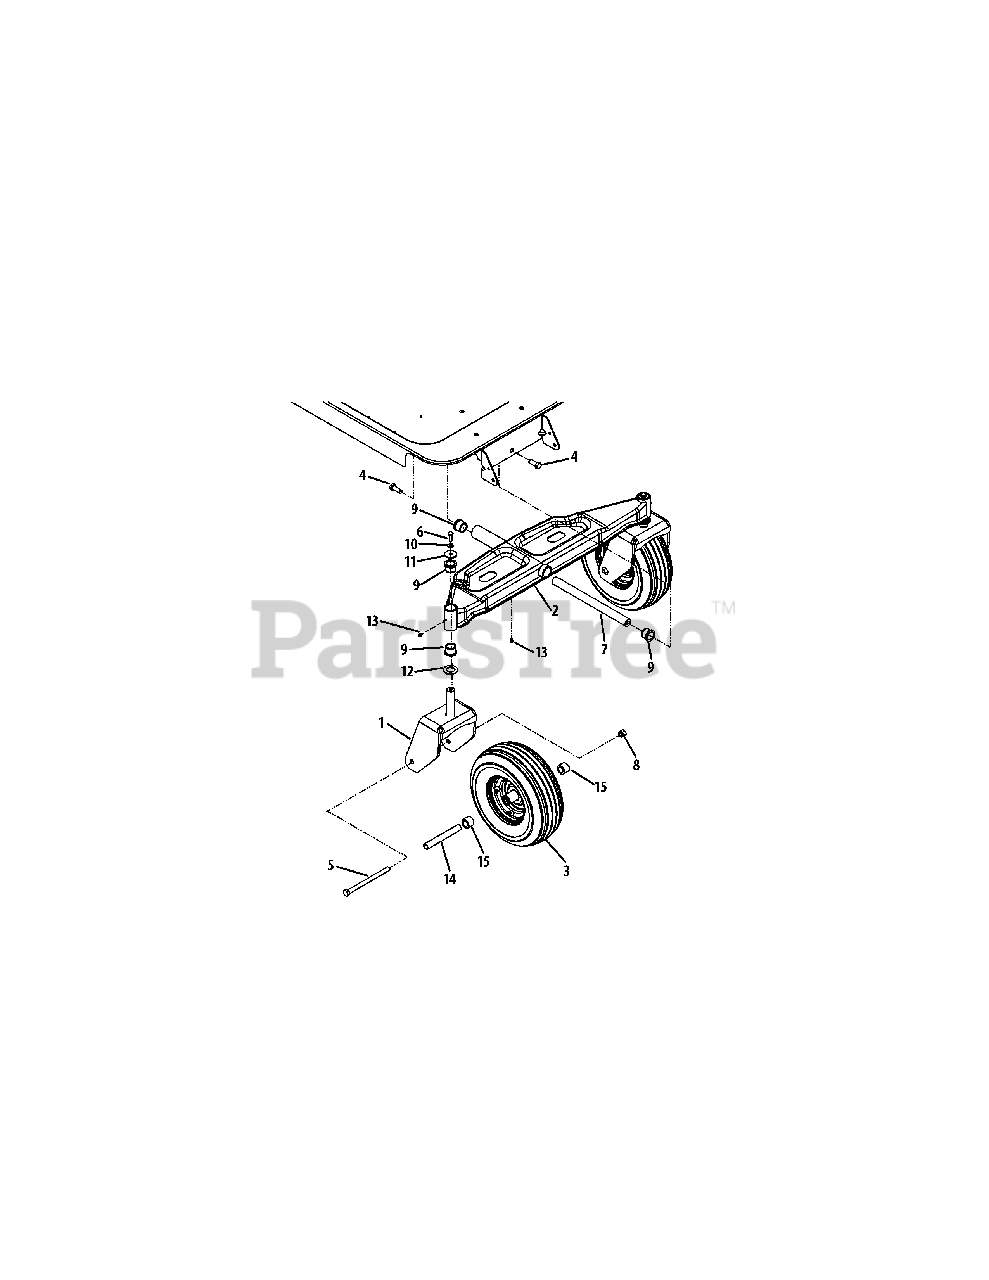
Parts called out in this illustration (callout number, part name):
1	Castor Wheel Bracket
2	Front Pivot Axle
3	Wheel Assembly, 13 x 5-6
4	Hex Lock Screw, 1/2-13 x 1.25
5	Hex Cap Screw, 1/2-20 x 7.25
6	Hex Cap Screw, 3/8-16 x 1.0
7	Axle Shaft
8	Hex Insert Lock Nut, 1/2-13
9	Flange Bearing, 1.0 x 1.246
10	Lock Washer, 3/8
11	Flat Washer, .39 x 1.5 x .134
12	Flat Washer, 1.0 x 1.75 x .10
13	Lube Fitting, 3/16 Drive
14	Spacer, .51 x .75 x 5.825
15	Hub, .76 x 1.23 x .92
